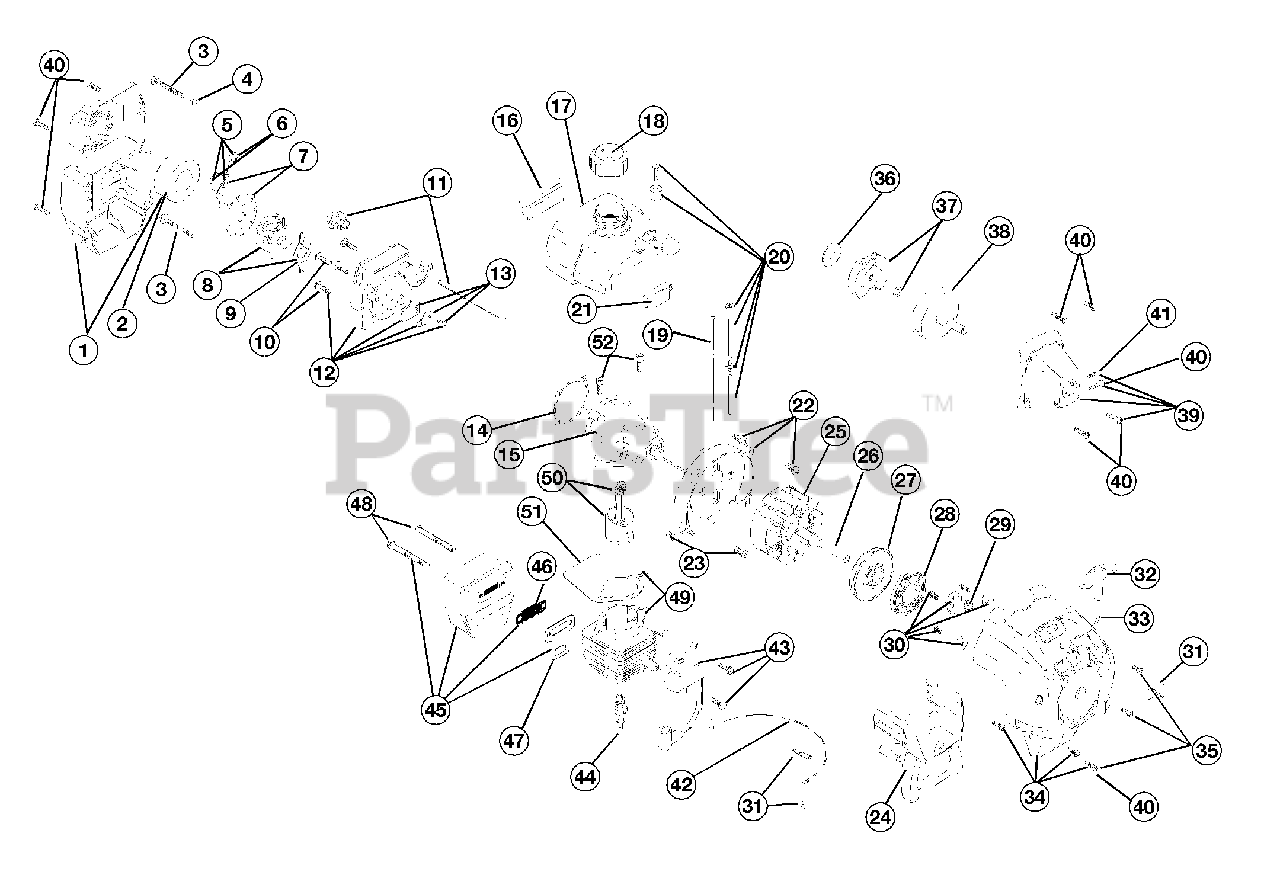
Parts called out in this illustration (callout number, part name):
1	Air Cleaner/Muffler Cover Assembly
2	Air Cleaner Filter
3	Carburetor Mounting Screw Assembly
4	Wavey Washer
5	Choke Lever Assembly
6	Choke Knob and Screw
7	Choke Lever and Plate
8	Carburetor Assembly
9	Carburetor Gasket
10	Carb Mount Screw
11	Primer and Hose Assembly
12	Carb Mount Assembly
13	Reed Assembly
14	Carburetor Mount Gasket
15	Crank Case Service Assembly
16	Rear Mounting Pad
17	Fuel Tank Assembly
18	Fuel Cap Assembly
19	Fuel Return Line
20	Fuel Line Assembly
21	Front Mounting Pad
22	Shroud Assembly
23	Shroud Screw
24	Shroud Extension & Stand
25	Flywheel Assembly
27	Recoil Pulley Assembly
28	Recoil Spring
29	Rope Guide
30	Pulley Retainer Assembly
31	Switch Assembly
32	Pull Handle
34	Starter Housing Assembly
35	Housing Screw
36	Clutch Washer
37	Clutch Rotor Assembly
38	Clutch Drum Assembly
39	Clutch Cover Assembly
41	Anti-Rotation Screw
42	Wire Lead
43	Module Assembly
44	Spark Plug
45	Muffler Assembly
46	Spark Arrestor Screen
47	Exhaust Gasket
48	Muffler Mounting Bolt Assembly
49	Cylinder Assembly
50	Piston and Rod Assembly
51	Cylinder Gasket
52	Cylinder Bolt
